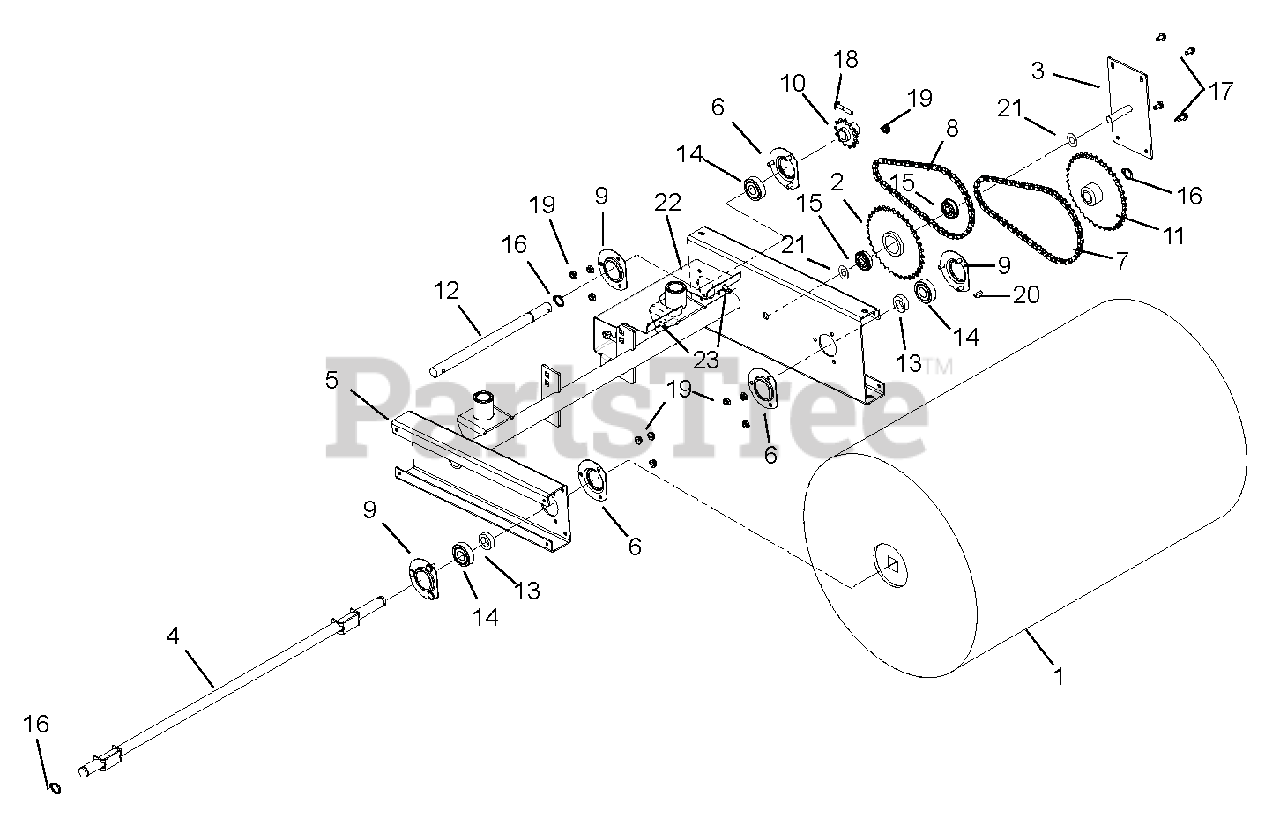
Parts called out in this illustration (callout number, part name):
1	BRUSH, 18"DIA X 28"WIDE
2	SPROCKET, REDUCTION IDLER
3	PLATE, IDLER REDUCTION MOUNT
4	SHAFT, 28" BRUSH
5	FRAME, POWER BROOM-DELUXE
6	BEARING FLANGE
7	CHAIN, #40-54 LINKS
8	CHAIN, #41-50 LINKS
9	BEARING FLANGE
10	SPROCKET, DRIVE
11	SPROCKET, DRIVEN
12	SHAFT, TRANSMISSION
13	SPACER .755X1.250X.370
14	BRG-BALL .750X1.750X.50
15	BRG-BALL .50X1.38X.438 SEALED
16	RG-RTNG-EXT .689X.078
17	SCR-TAP .25-20X.50 HWH TR YWZ
18	@BLT-HEX .25-20X1.75 GR5 YWZC
19	@NUT-LK-TOP-FLG .25-20 YWZC
20	KEY-WDRF .188X.75X.313 SAE 9
21	@WSHR-FL-STL.563X1.38X.109YWZC
22	COVER, FRONT SHAFT - CE
23	SCR-TAP .25-20X.50 LGHWH TR YZ
